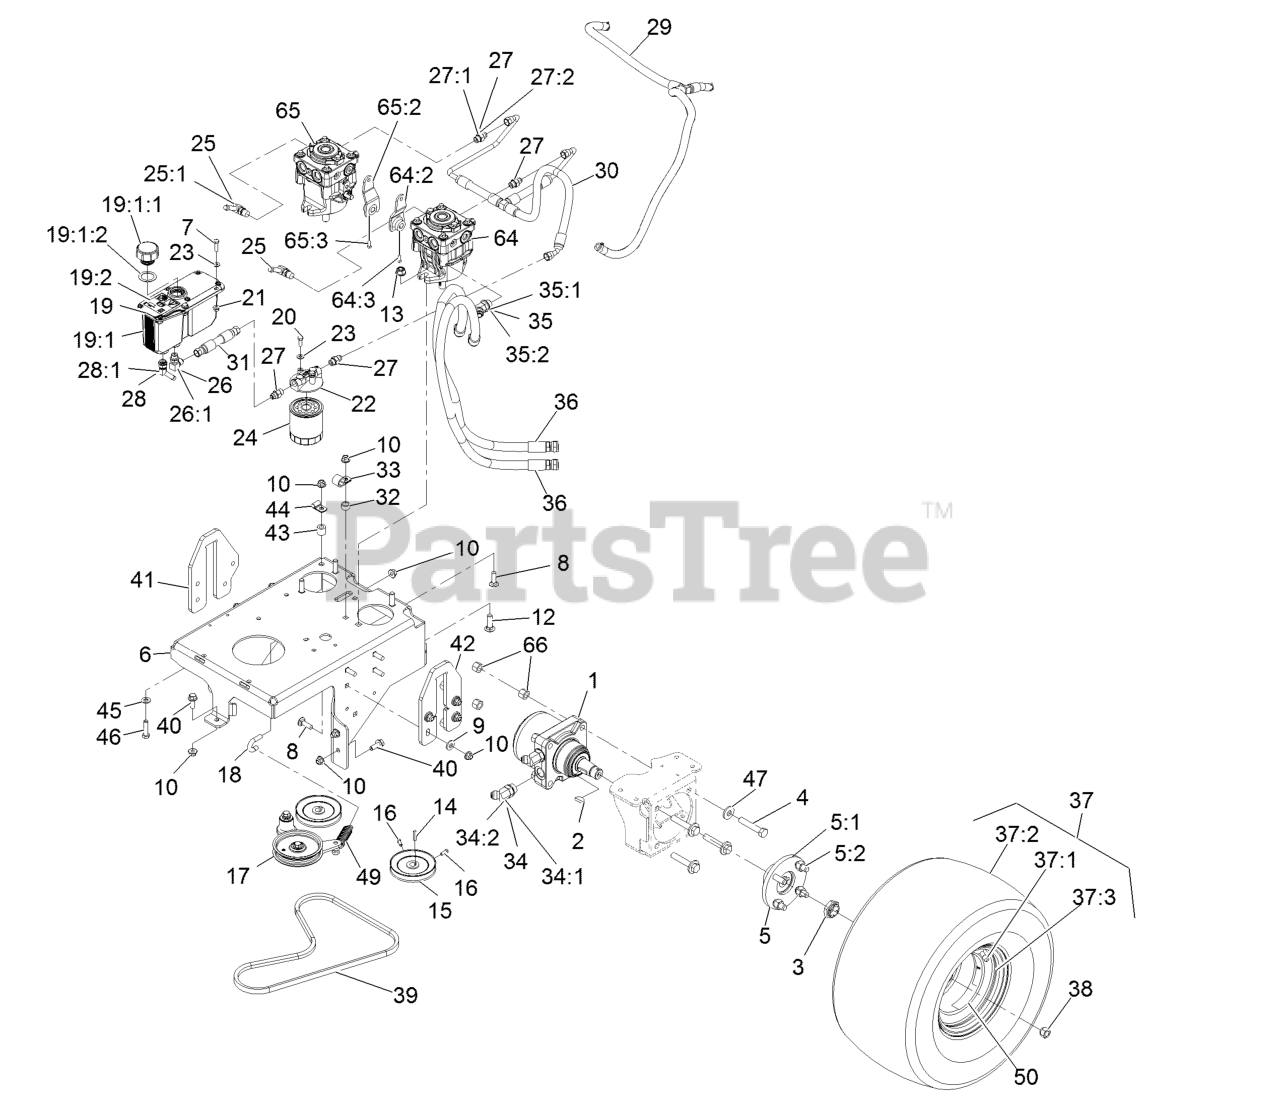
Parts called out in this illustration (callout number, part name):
1	MOTOR-WHEEL
2	KEY-WOODRUFF
3	LOCKNUT
4	SCREW-HH
5	WHEEL HUB / STUD ASM
5:1	HUB-WHEEL
5:2	STUD-TYPE, DRIVE
6	WELDMENT, FRAME
7	SCREW-HH
8	BOLT-CARR
9	WASHER-BELLEVILLE
10	NUT-HF, NI
12	SCREW-HH
13	NUT-HF, NI
15	PULLEY-PUMP
16	SCREW-SET
17	PUMP IDLER ASM
18	ANCHOR, SPRING
19	RESERVOIR ASM
19:1	Reservoir-HYD
19:1:1	Cap-Reservoir, HYD
19:1:2	GASKET-CAP
19:2	DECAL-WARNING
20	SCREW-HH
21	NUT-HHF
22	HEAD-FILTER
23	WASHER-FLAT
24	FILTER-25 MICRON, BI-DIRE
25	FITTING-ELBOW, 90
25:1	O-RING
26	FITTING-ELBOW, 90 DEG
27	FITTING-STRAIGHT
28	FITTING-BARBED, 45 DEG
28:1	O-RING
29	HOSE ASM-HYD LP 3/8
30	HOSE ASSEMBLY - CHARGE
31	HYD HOSE ASM
32	SPACER-WHEEL
33	CLIP-LOOM
34	FITTING-HYD, 45 DEG
35	FITTING-HYD, 45 DEG
36	HYD HOSE ASM
37	WHEEL/TIRE ASM
37:1	RIM-8 INCH
37:3	Stem-Valve
38	NUT-LUG
39	BELT-V, LOWER PTO
40	SCREW-HHF 3/8-16 X 1
41	PLATE-LIFT, RH
42	PLATE, LIFT LH
44	CLIP-TUBE
45	WASHER-FLAT
46	SCREW-HH
47	WASHER-SPRING
49	SPRING-EXTENSION
50	DECAL-TORQUE, WHEEL HUB LUG
64	PUMP W/ARM - LEFT
64:2	ARM-HYDRO
64:3	SCREW-SET
65	PUMP W/ARM -RIGHT
65:2	ARM-HYDRO
65:3	SCREW-SET
66	NUT-LOCK, NI
